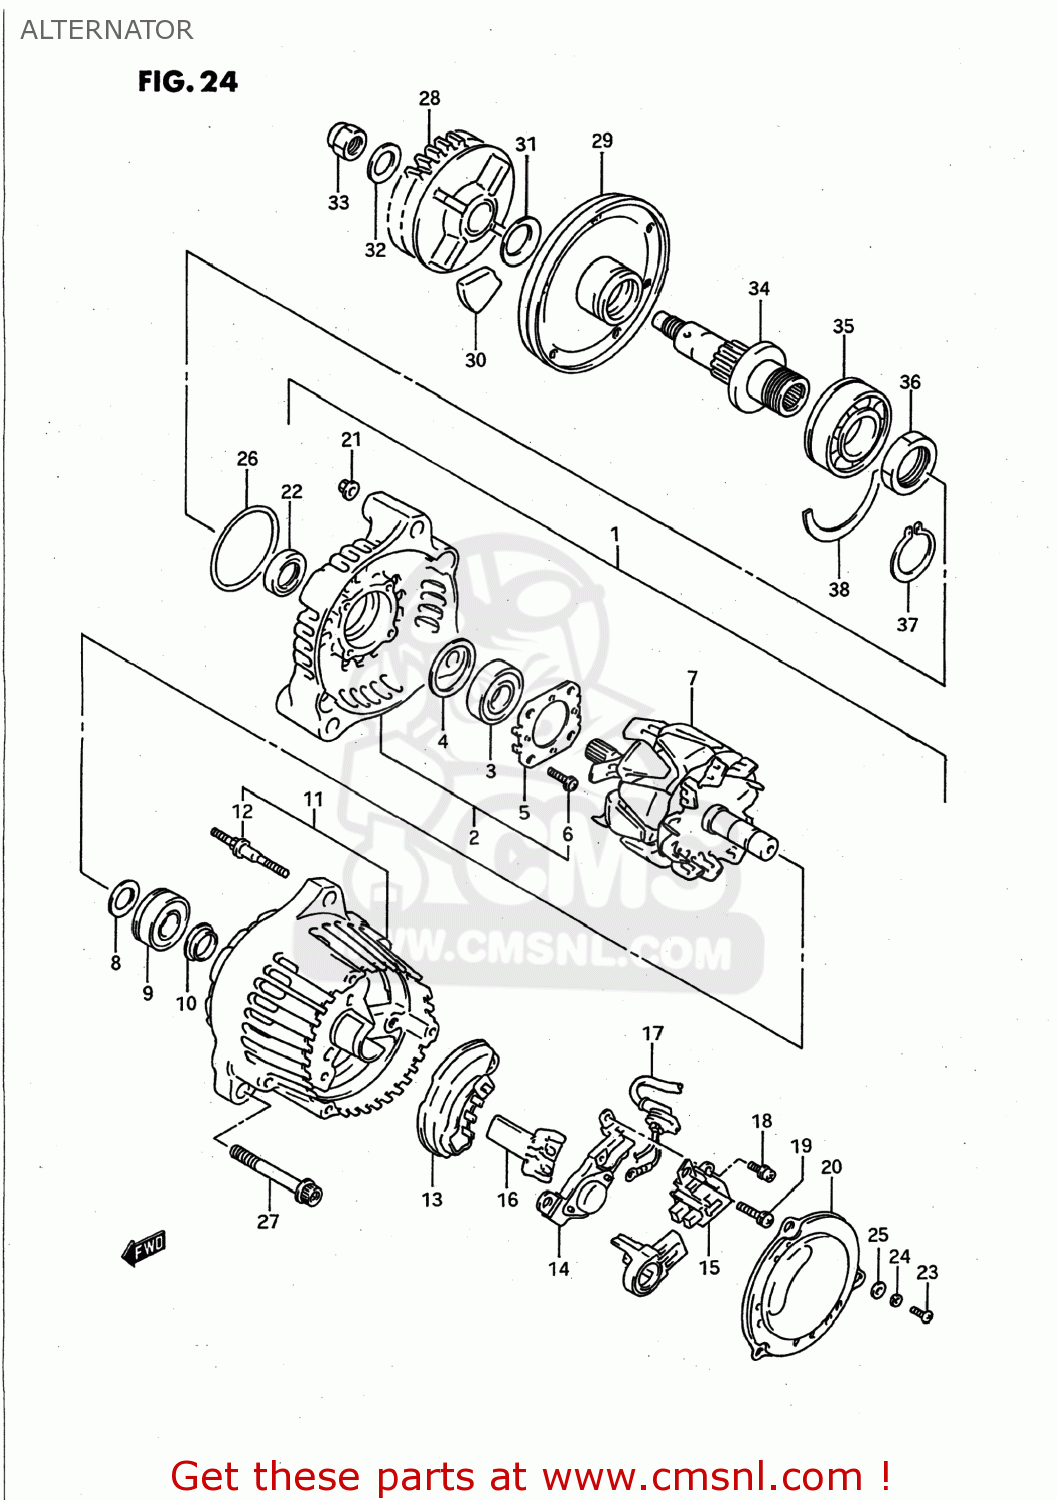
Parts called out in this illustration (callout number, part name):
1	ALTERNATOR ASSEMBLY
2	FRAME,DRIVE END
3	BEARING
4	COVER,BEARING
5	RETAINER,BEARING
6	SCREW,BEARING RETAINER
7	ROTOR ASSEMBLY
8	COVER,BEARING
9	BEARING
10	COVER(2)
11	FRAME,END
12	STUD BOLT
13	HOLDER,RECTIFIER
14	REGULATOR
15	HOLDER,BRUSH
16	COVER,RECTIFIER
17	WIRE,LEAD
18	SCREW
19	SCREW
20	COVER
21	NUT
22	SEAL SET,OIL
23	SCREW
24	WASHER,LOCK
25	WASHER,5MM
26	O RING
27	BOLT
28	GEAR,GENERATOR DRIVEN
29	HOUSING,GENERATOR DAMPER
30	DAMPER,GENERATOR
31	WASHER
32	WASHER
33	NUT
34	SHAFT,GENERATOR DRIVE
35	BEARING(25X52X15)
36	NUT
37	CIRCLIP
38	C RING
